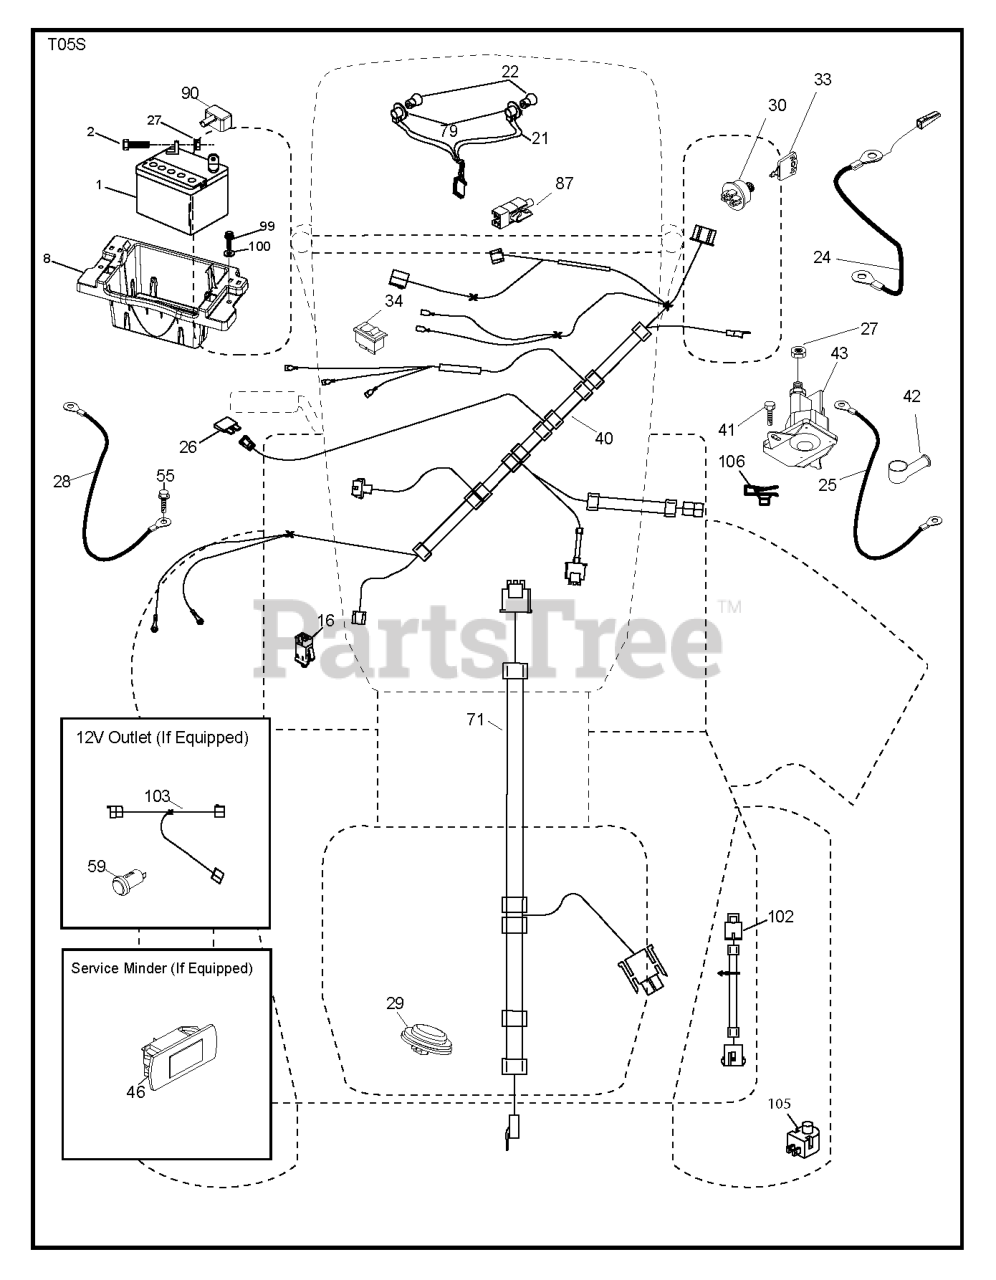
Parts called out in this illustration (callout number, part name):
1	Battery 12 Volt 25 Amp
2	BOLT.HEX.1/4.X.3/4.DICHROMATE
8	TRAY.BATTERY.FRNT.CARB W/SNAPS
16	SWITCH INTERLOOK PUSH-IN
21	HARNESS.LIGHT W/4152J BULBS
24	CABLE.FRBATT.W/WIRE.8GA.8
25	CABLE.BATT.RED.8GA.17
25	CABLE.STARTER.8GA.17.5
26	FUSE 20AMP
27	NUT
28	CABLE.BLACK.18"REAR.BA
28	CABLE.GROUND.REAR.BATTERY.8G
29	SWITCH.SEAT.DELTA.OPC.
30	SWITCH.IGN.DELTA.W.LGH.ROS
33	KEY.CHAIN.BLISTER.PACK.GEN.USA
40	HARNESS.IGN.DASH.CBL.YTGT.PRED
41	SCREW
42	TERMINAL COVER
43	SOLENOID.W/BRASS.PLUNGER
46	GUAGE.SRVCMNDR.HRMTR.
55	SCREW 5/16"
71	HARNESS.CHASSIS.RRBATT.RDYSTRT
79	BULB HOLDER ASM.
87	SWITCH.INTRLCK.CLUTCH.
90	COVER.TERMINAL.BATTERY
99	SCREW HEXWSHR 1/4-20X3/4
102	HARNESS.PIGTAIL.VARIATOR.SD
105	REVERSE SWITCH
106	1/4-20 U NUT
